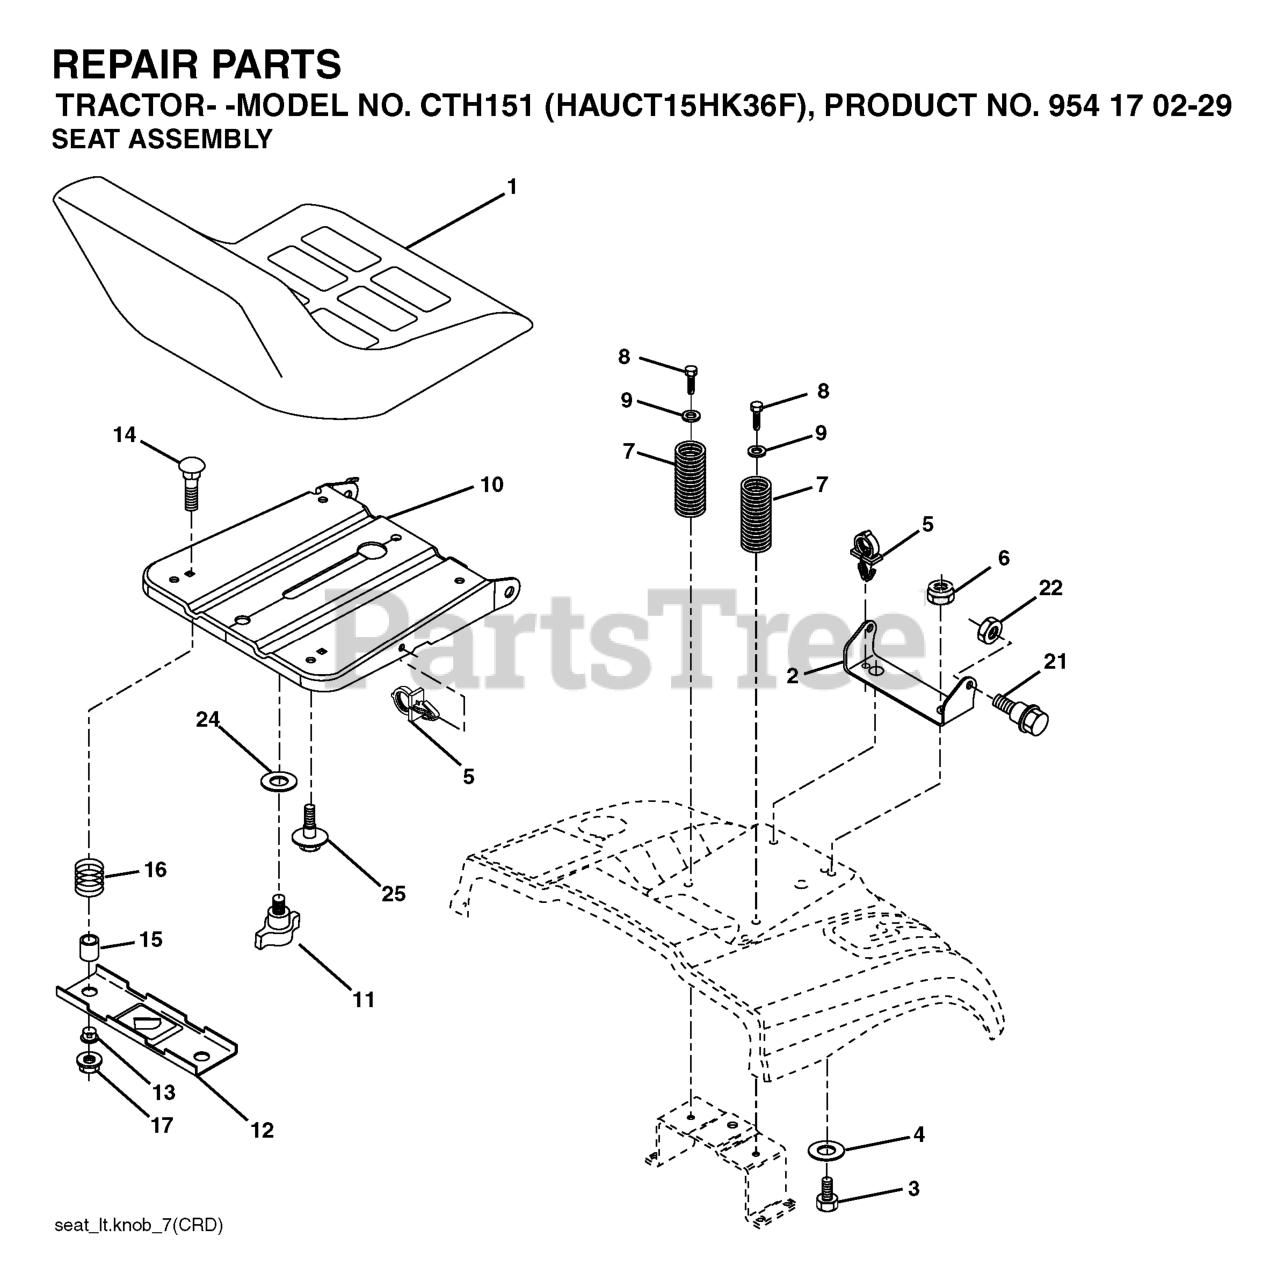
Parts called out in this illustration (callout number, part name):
1	SEAT
2	SEAT PIVOT BRKT
3	BOLT, HEX 3/8-16X1
6	NUT
7	SPRING COMPRESSION
8	SCREW 3/8-16X1
9	WASHER
10	PAN SEAT
11	KNOB.SEAT.ADJ.WINGNUT
12	BRKT SWITCH
14	BOLT.ROUND.HEAD.SQUARE.NECK
15	SPACER SPLIT 28X.96
17	NUT T
21	BOLT.SHOULDER.5/16-18
22	NUT.71038.31-18.HEX.NYLOCK
25	BOLT,SHOULD
